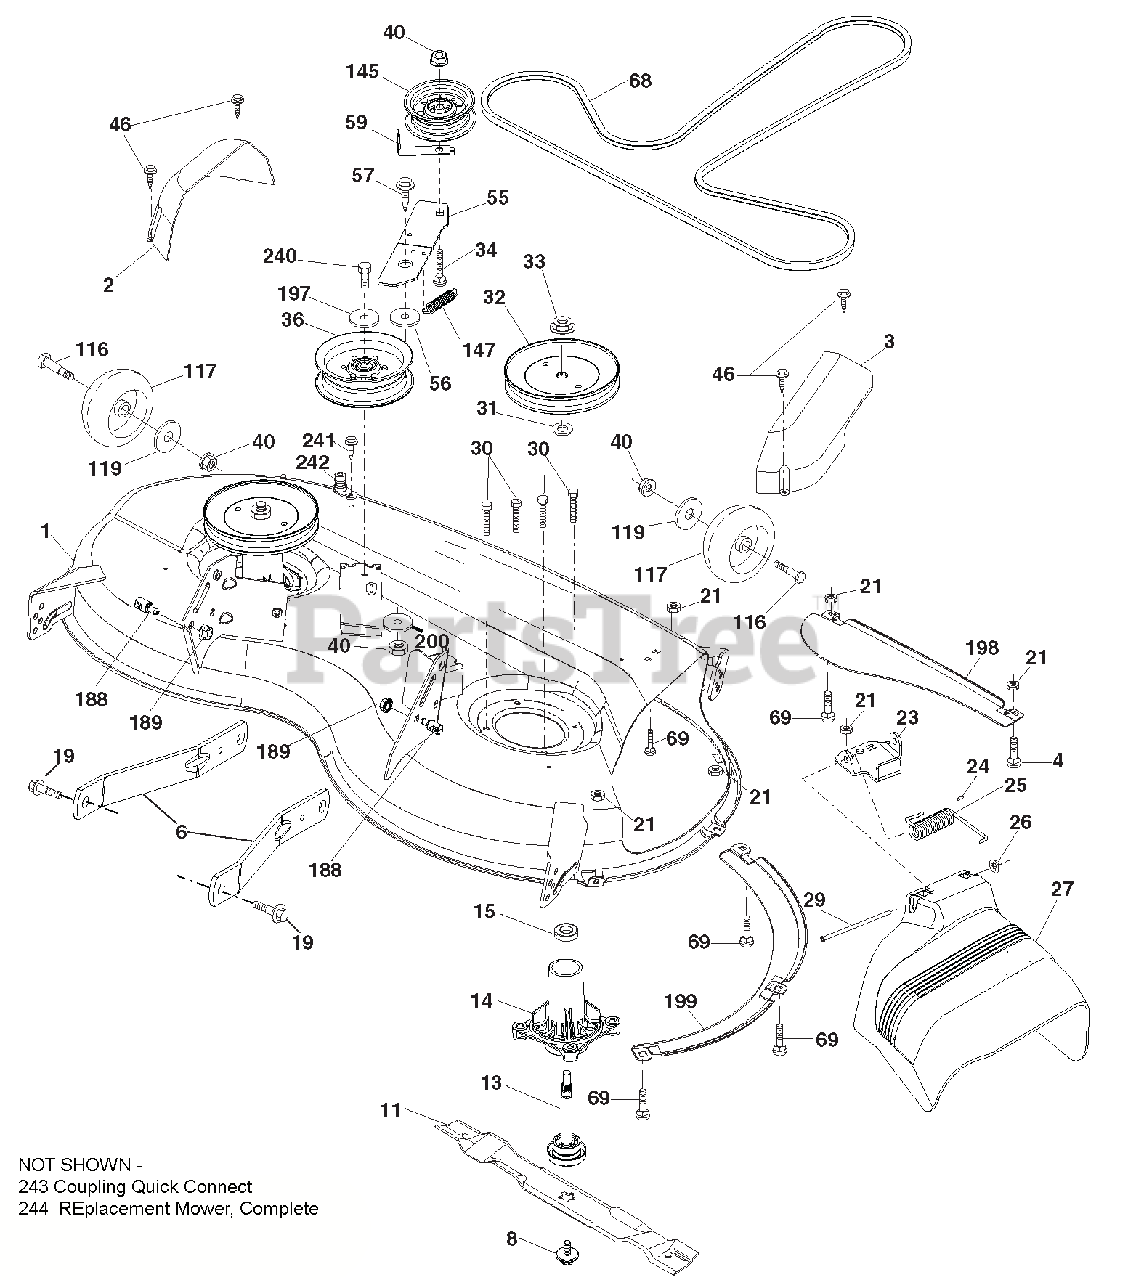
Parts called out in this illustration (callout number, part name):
1	MOWER HOUSING
2	COVER.MANDREL.LH.46"
3	COVER.MANDREL.RH.46"
4	BOLT.HEX.HD.1/4-20UNC X 3/4
6	ARM.SUSPENSION.MOWER.REAR.LD
8	BOLT/WASHER ASM.7/16-20.UNF
11	BLADE.MOWER.46"HI LIFT BAGGER
13	SHAFT ASM.MNDRL.N/GREASEABLE38
14	HOUSING.MANDREL.4PT.SERVICE
15	BEARING.BALL.MANDREL
19	BOLT.SHOULDER
21	Nut, Hex, Crownlock 5/16-18
23	BRACKET.DEFLECTOR.38/42"2005
24	CAP.SLEEVE..80X.112.BLK.MOWER
25	SPRING.TORSION.DFL.38/42/46.GR
26	NUT.PUSH.PHOS.& OIL
27	SHIELD.DEFLECTOR.MOWER 46"BLK
29	ROD.HINGE.42/46"
30	SCREW.THD ROLL.DOD PT.HEX
31	WASHER.SPACER.MANDREL
32	PULLEY.MANDREL.5.438 PD.42"
32	MANDREL ASM.SUB.N-GRS.4 BOLT
32	SHAFT ASSEMBLY, AND BEARING
32	ONLY - PULLEY/NUT/WASH-ER AND BLADE
32	BOLT/WASHERS NOT INCLUDED)
33	NUT.FLANGE.LOCK.TOP
34	BOLT.CARR.SH.3/8-16X1-1/2.GR5
36	PULLEY.IDLER.4.50.RAW
40	Nut, Hex, Flangelock 3/8-16
46	SCREW.THD.ROLL.1/4-20 X 5/8
55	IDLER.ARM
56	SPACER.RETAINER
57	SCREW.3/8-16X1.SMGML.TAP/R.BLK
59	GUARD.TUV.IDLER
68	V-BELT.DRIVE.MWR.MECHANICL.46"
69	BOLT.5/16-18HEX.WHS.HD.LCKSERR
116	BOLD SHLD "A" 2.41 "B" 1.66
117	WHEEL.GAGE.HALF.SPOKED
119	Washer 3/8 x 7/8 x 14 Ga.
145	PULLEY.IDLER 48"PRIMARY
188	STUD.FASTNER.W/'D'ANTI-ROTATIO
189	Nut, Lock Hex Flange 5/16-18 u
197	Washer 13/32 x 13/16 x 12 Ga.
198	BAFFLE.CENTER.FRONT
199	BAFFLE.FRONT.RH
200	WASHER.13/32 X 1 X 1/2.11GAHRD
240	BOLT.FIN.HEX.3/8-16X 2-1/4 GR5
242	PORT WASHOUT
